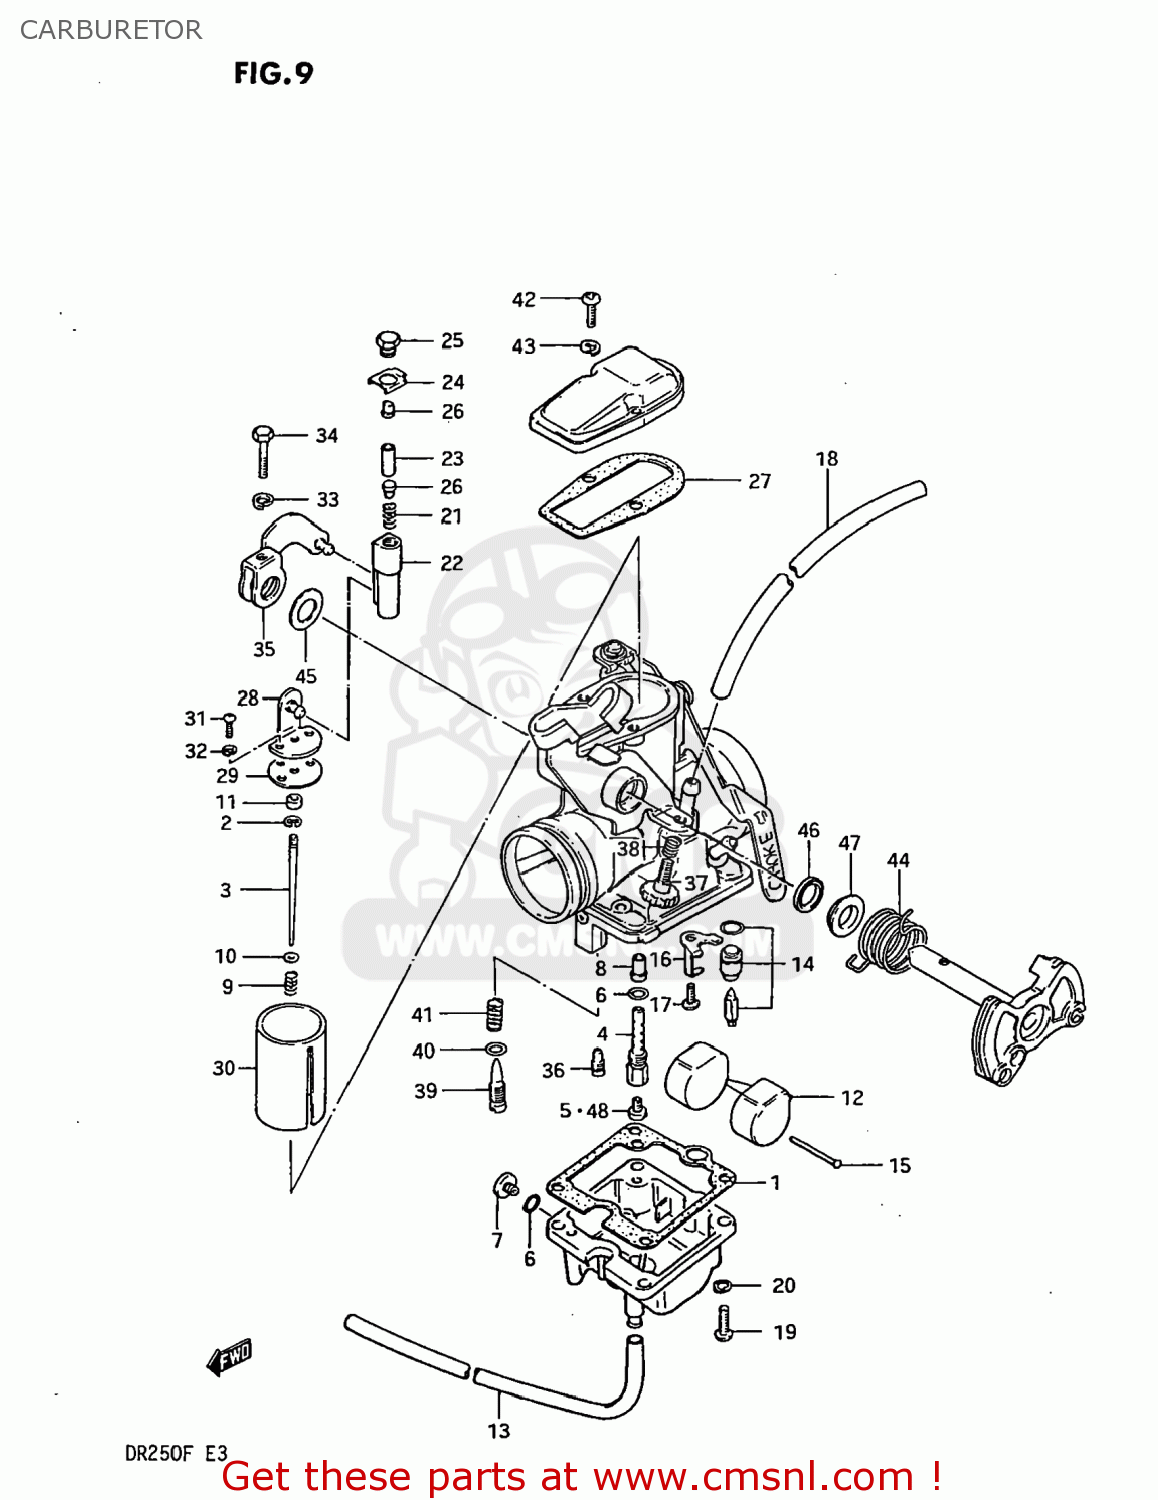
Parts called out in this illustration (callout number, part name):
1	GASKET,FLOAT CAHMBER (NAS)
2	CLIP
3	NEEDLE JET
4	PIPE,BLEEDER
5	JET,MAIN(112.5)
6	O RING
7	SCREW
8	JET,NEEDLE
9	SPRING
10	WASHER,JET NEEDLE
11	RING
12	FLOAT
13	HOSE
14	VALVE ASSY,NEEDLE
15	PIN,FLOAT
16	PLATE
17	SCREW 4X6
18	HOSE
19	SCREW
20	LOCK WASHER
21	SPRING,CARBURETOR
22	LEVER ASSEMBLY
23	SPRING
24	PLATE,CARBURETOR
25	SCREW
26	PIN,CARBURETOR
27	GASKET,TOP (NAS)
28	CONNECTOR
29	PLATE,THROTTLE VALVE
30	VALVE,THROTTLE
31	SCREW
32	LOCK WASHER
33	WASHER
34	BOLT
35	ARM,THROTTLE
36	JET
37	ADJUSTER,THROTTLE
38	SPRING
39	ADJUSTER,PILOT
40	O RING
41	SPRING,PILOT AIR SCREW
42	SCREW
43	LOCK WASHER
44	SPRING
45	RING,THROTTLE SHAFT
46	SEAL
47	RING
48	JET
